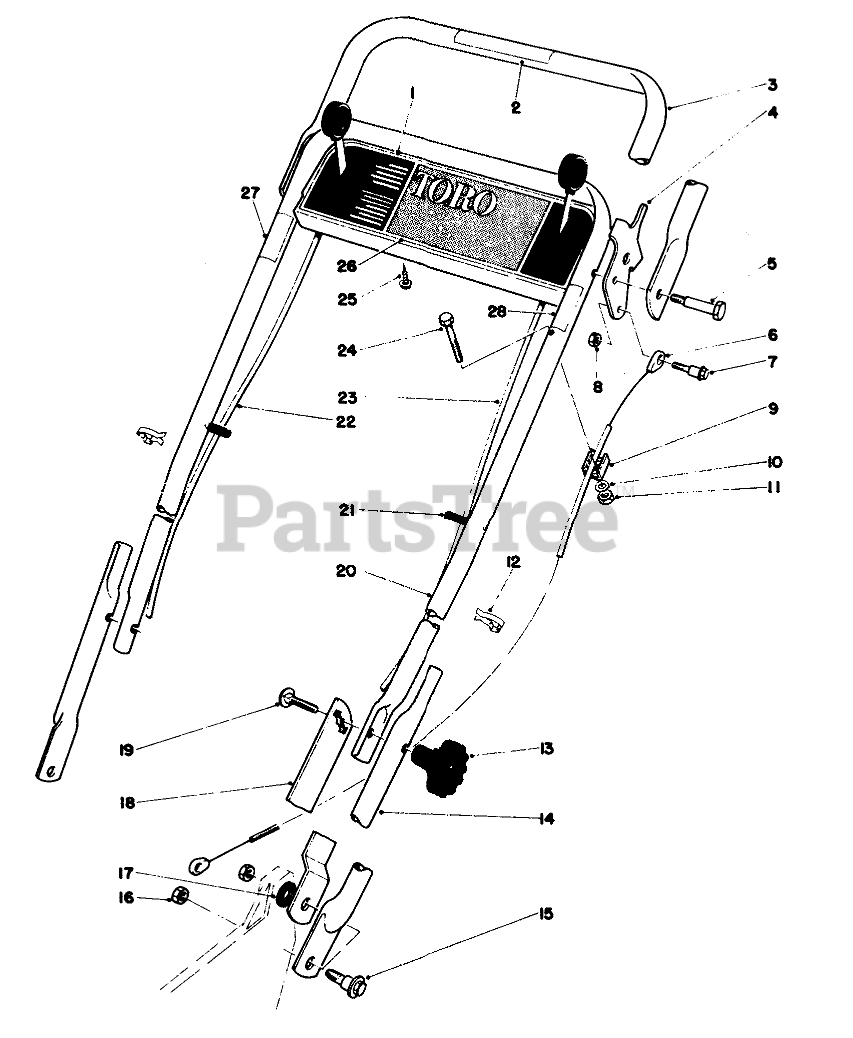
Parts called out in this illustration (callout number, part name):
1	Control Panel
2	Decal-Traction Control (German)
3	Demand Handle
4	Demand Handle Stop
5	BOLT-SHOULDER
6	DEMAND HANDLE CABLE
7	Shoulder Bolt
8	NUT-HEX, SIDE DEFORM
9	CLAMP-CABLE
10	WASHER-FLAT
11	NUT-LOCK, NI
12	BOWDEN CLIP
14	LOWER HANDLE
15	SCREW-SHOULDER
16	Nut
17	SPACER
18	Handle Latch L.H.
19	SCREW-CARR
20	Upper Handle
21	CAP-VINYL
22	GROUND SPEED CONTROL
23	Throttle Control
24	SCREW-HH
25	SCREW-HWHTF
26	Decal-Control Panel (German)
27	Decal-Control Shift (German)
28	Decal-Throttle
